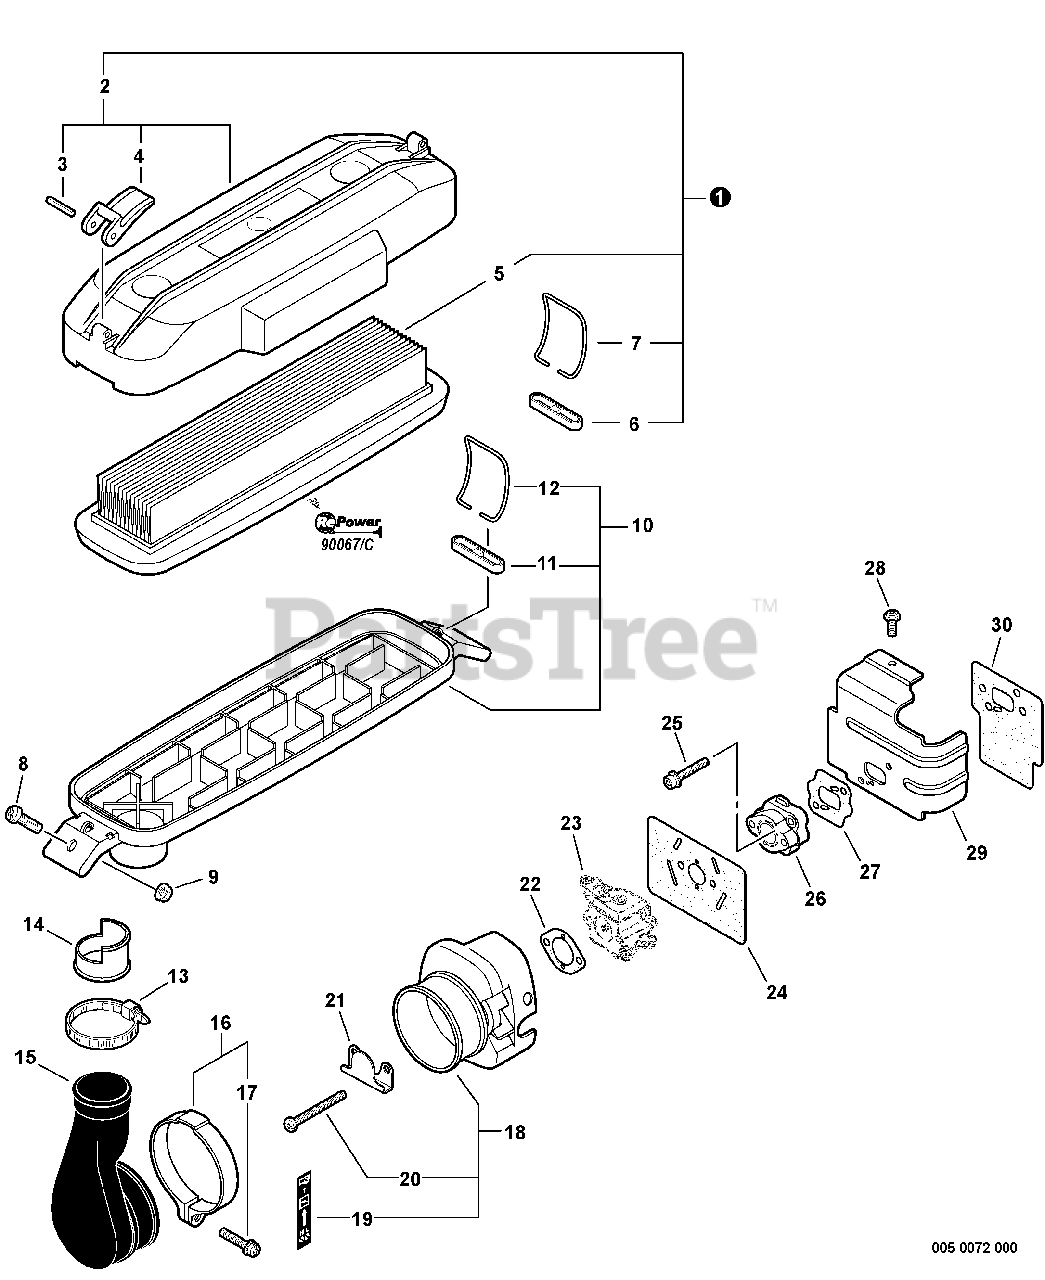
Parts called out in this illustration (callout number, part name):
1	AIR FILTER KIT
2	AIR FILTER COVER ASSY
3	PIN - SPRING -- 3X25
5	FILTER, AIR
6	RETAINER
7	RING, RETAINING
8	SCREW - 5X14
9	NUT - 5 -- FLANGE
10	AIR FILTER CASE ASSY
11	RETAINER
12	RING, RETAINING
13	CLAMP, HOSE
15	ADAPTOR, INTAKE
16	CLAMP KIT
17	SCREW - 5X25
18	BRACKET KIT - PLASTIC
19	LABEL - CHOKE
20	SCREW - 5X57
21	PLATE, PREVENT
22	GASKET, INTAKE
23	CARBURETOR
24	GASKET, INTAKE
25	SCREW - 5X25
26	INSULATOR, INTAKE
27	GASKET, INTAKE
28	SCREW - 5X10
29	COVER, CYLINDER - INTAKE
30	SHIELD, INTAKE
31	RePower TUNE-UP KIT
